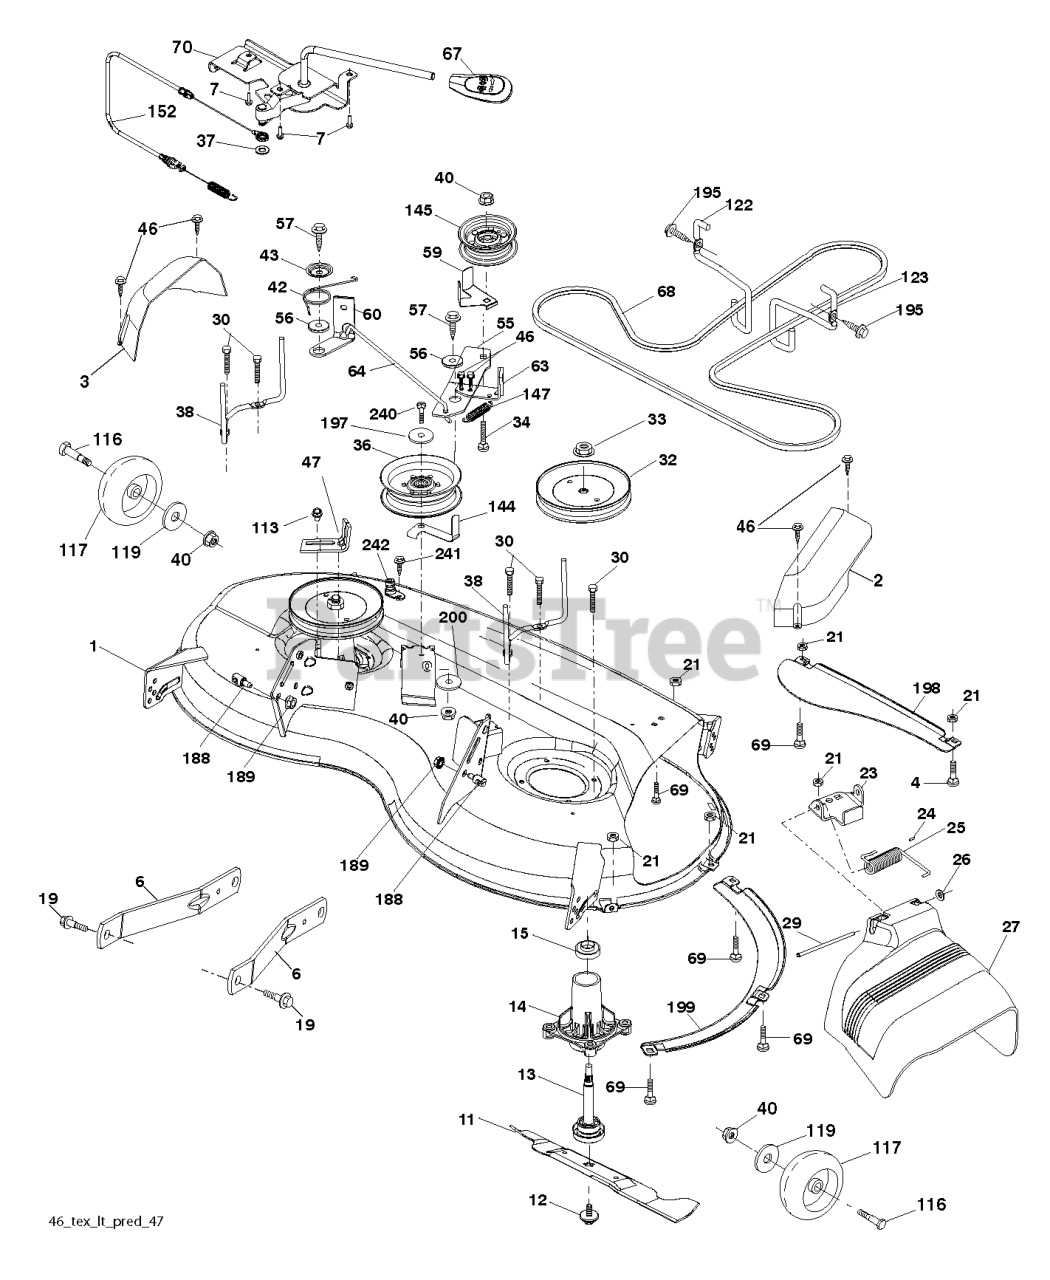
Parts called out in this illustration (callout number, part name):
1	DECK.WELDMENT.46.2GA.WHLS.GRAY
2	COVER.MANDREL.RH.46"
3	COVER.MANDREL.LH.46"
4	BOLT
6	ARM.SUSPENSION.MOWER.R
7	SCREW.#10 X 0.750.BOS
8	BOLT.WASHER.ASM.7/16-2
11	BLADE.MOWER.46".HI.LIFT
13	SHAFT.ASM.MDRL.N/GREASE.38
14	RP.HOUSING.MANDREL.4PT.
19	BOLT.SHOULDER
21	LOCKNUT
23	BRKT.DEFLECTOR.38"2005+
24	CAP-SLEEVE LT
25	SPRING.TORSION.DEFLECT
26	NUT PUSH M
27	SHIELD.DEFLECTOR.MOWER.46"BLAC
29	ROD.HINGE
30	SCREW, WASHER HEAD
31	WASHER.SPACER.MANDREL
32	PULLEY.MANDREL.5.438.PD
33	NUT.FLANGE.LOCK.TOP
34	BOLT.3/8-16X1.50
36	PULLEY.IDLER.2006
37	WASHER
38	KEEPER.BELT.MANDREL.PULLEY
40	NUT LOCK FLG 3/8-16 UNC
42	SPRING.TORSION.BRAKE
43	SRPING.TORSION.RETAINE
46	SCREW.1/4-20X5/8
47	BRKT.CLUTCH.CABLE
55	IDLER.ARM
56	SPACER.RETAINER
57	SCREW 3/8-16X1
59	GUARD, BELT
60	ARM BRAKE MOWER RH 38"
63	ARM BRAKE MOWER
64	LINKAGE BRAKE
67	HANDLE.CLUTCH.CABLE.LT
68	V-BELT
69	BOLT
70	CLUTCH.ASM.MANUAL.YT.PREDATORQ
113	BOLT.5/16HEX.WHS.HD
116	BOLT.SHOULDER.3/8-16X3-5/8.
117	RP WHEEL. GUAGE RALLY
119	WASHER
122	KEEPER BELT ENGINE LH
123	KEEPER BELT RH
144	KEEPER.BELT.MOWER
145	PULLEY.IDLER.48"PRIMARY
147	SPRING RETURN
152	CABLE.MECHANICAL.CLUTCH
188	STUD.FASTNER.W/ANTI-ROTATE
189	NUT LOCK HEX FLANGE 5/16-18
195	SCREW, 3/8-16X3/4
197	WASHER
198	BAFFLE CENTER FRONT
199	BAFFLE FRONT RH
200	WASHER.13/32 X 1 X 1/2.11GUARD
240	BOLT-HEX EAK
241	SCREW.TT.#10-32X.5.3/8.FLANGE
242	PORT.WASHOUT
